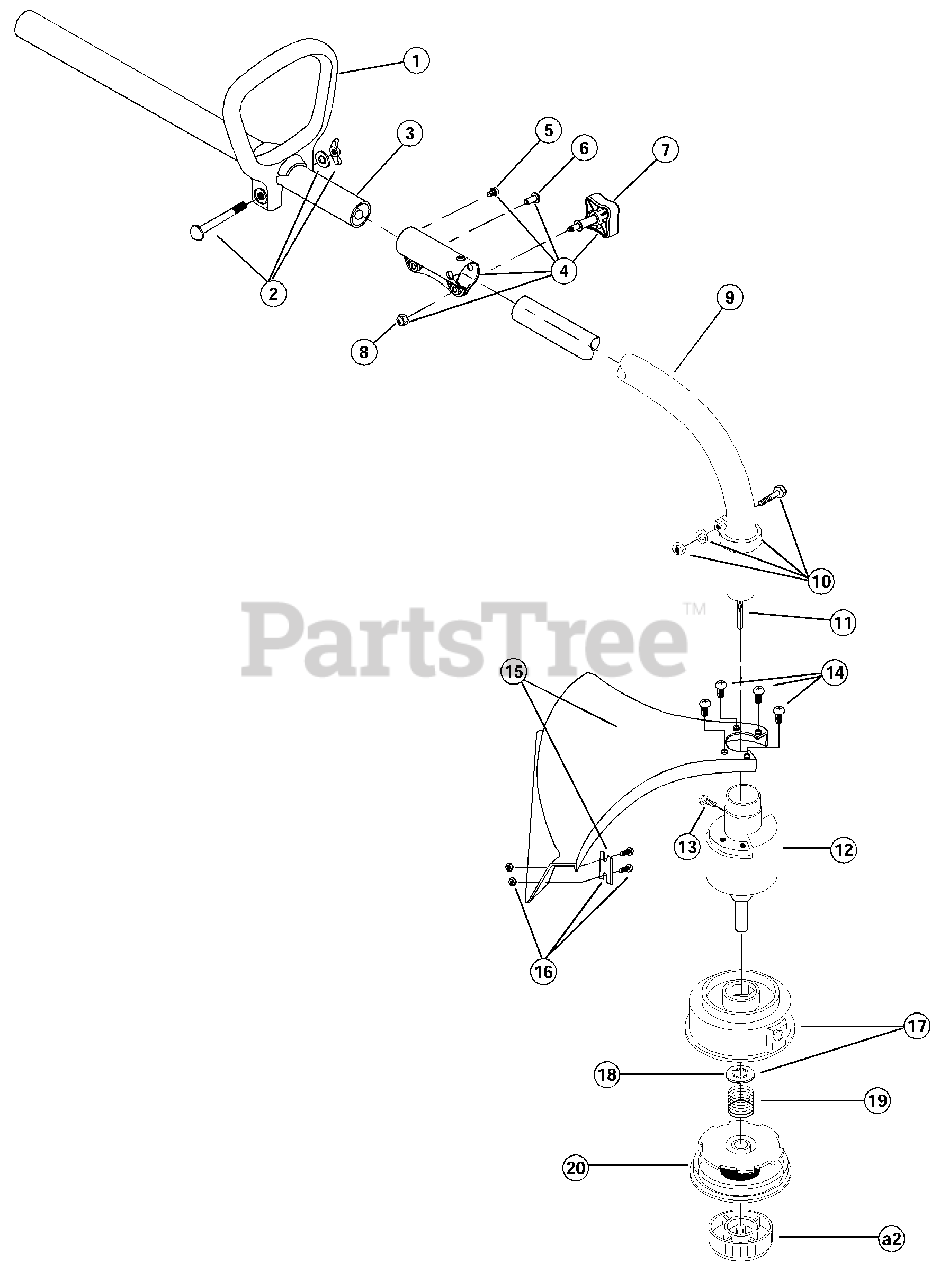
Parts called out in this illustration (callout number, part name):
1	D-Handle
2	D-Handle Hardware Assembly
3	Upper Drive Shaft Housing Assembly
4	Split-Boom Coupler
7	Adjustment Knob
8	Knob Retaining Nut
9	Lower Drive Shaft Housing Assembly
10	Lower Clamp Assembly
11	Flexible Drive Shaft
12	Bushing Housing Assembly w/shaft
13	Anti-Rotation Screw
14	Guard Mounting Screw Assembly
15	Guard and Blade Assembly
16	Blade Assembly
17	Outer Spool Assembly w/ Retainer
18	Retainer
20	Inner Reel
21	Bump Head Knob Assembly
